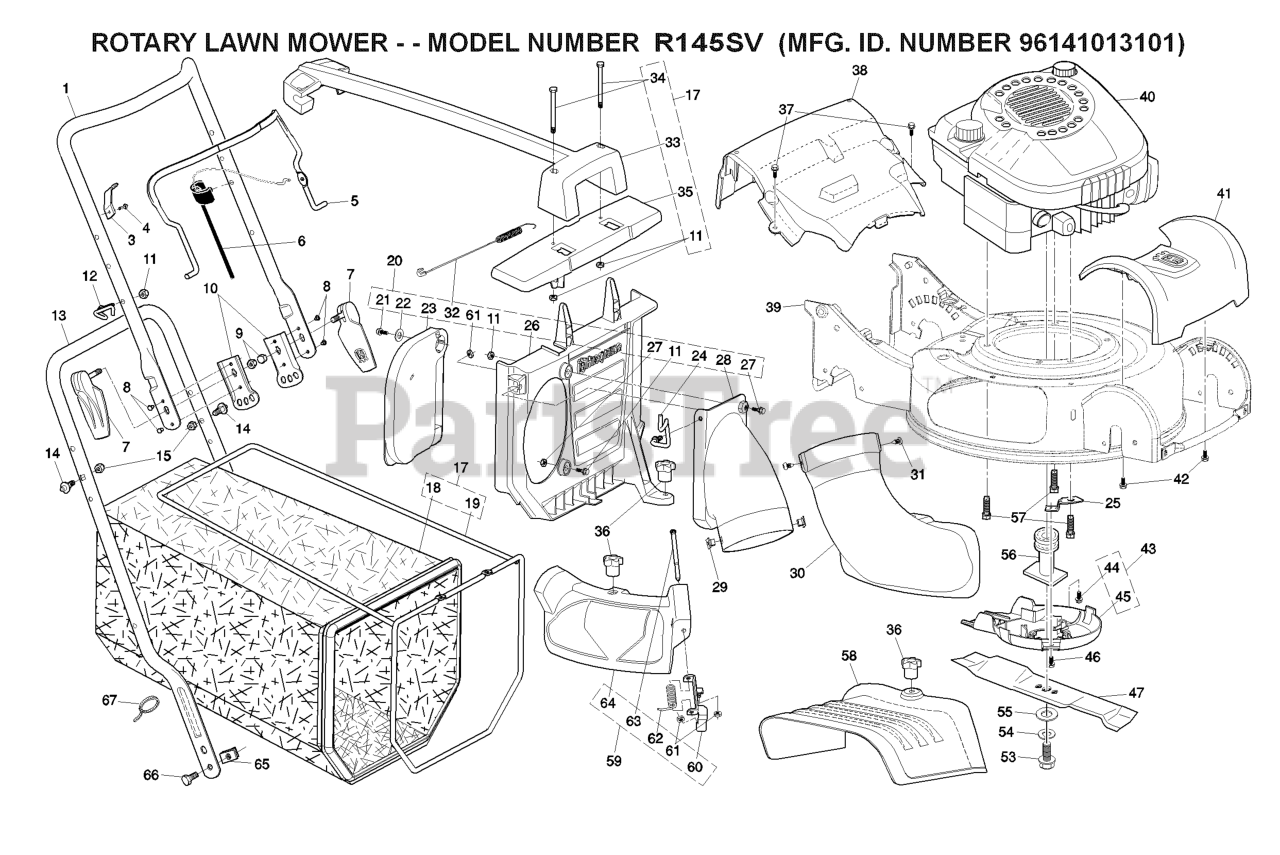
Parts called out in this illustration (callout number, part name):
1	HANDLE.ASM.UP.W/ADJ.BKT
3	BRACKET
5	BAIL CONTROL
6	CABLE.MZR.50.SNAP-IN
7	ASM.QUICK.RELEASE
9	Locknut, Hex 1/4-20
10	BRACKET.ADJ.3POS.GREY
11	NUT
12	RB GUIDE.ROPE.STD.BLK.ZIN WSL
14	STUD.QUICK.ADJUST
15	NUT.LOCK.5/16-18
22	WASHER
25	BRACKET
27	BOLT, SHOULDER
31	SCREW T-30 1/4-20 X
36	KNOB.MULCH.DOOR
37	SCREW, HEX WASHER HEAD
42	SCREW.HWH.13-16-5.8.BZP
44	HINGE SCREW
46	SCREW.HEX.WSH
47	BLADE.SWEPT.WING.45CM.H.TREAT
53	BOLT.HD.HEAD.3/8-24X2.50 (2 2)
54	LOCKWASHER
55	WASHER,HARDEN
56	ADAPTER.BLADE
57	BOLT 3/8-16X1-1/8
61	NUT.HEX.FLANGE.1/4
62	SPRING.MULCH.DOOR
63	ROD.HINGE.1/4"3.82"
64	DOOR.MULCH.GREY
67	TIE GUIDE
